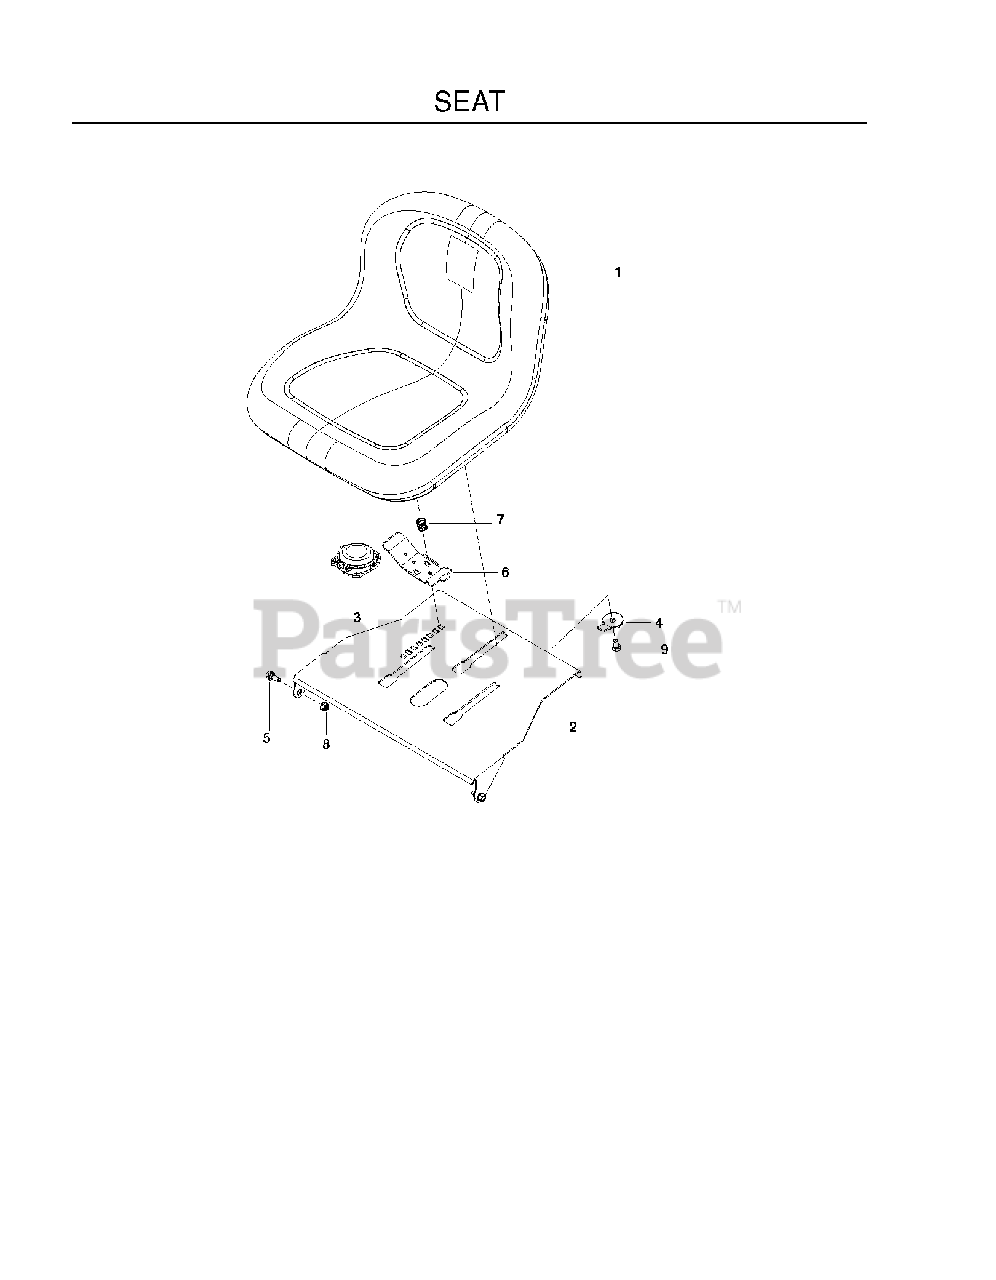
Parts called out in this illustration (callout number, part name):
1	RP SEAT, TH150, GREY, MILSCO
2	PLATE, SEAT, ORG
3	SWITCH, SEAT N/C
4	STOP, SEAT, BLACK
5	BOLT, SHOULDER
6	HANDLE.SLIDE.SEAT.TEX.BLACK
7	SPRING.LATCH.SEAT.TEX
8	5/16-18 NYLOC FLANGE NUT
9	HCS 3/8-16 X 5/8 GR 5 ZD
